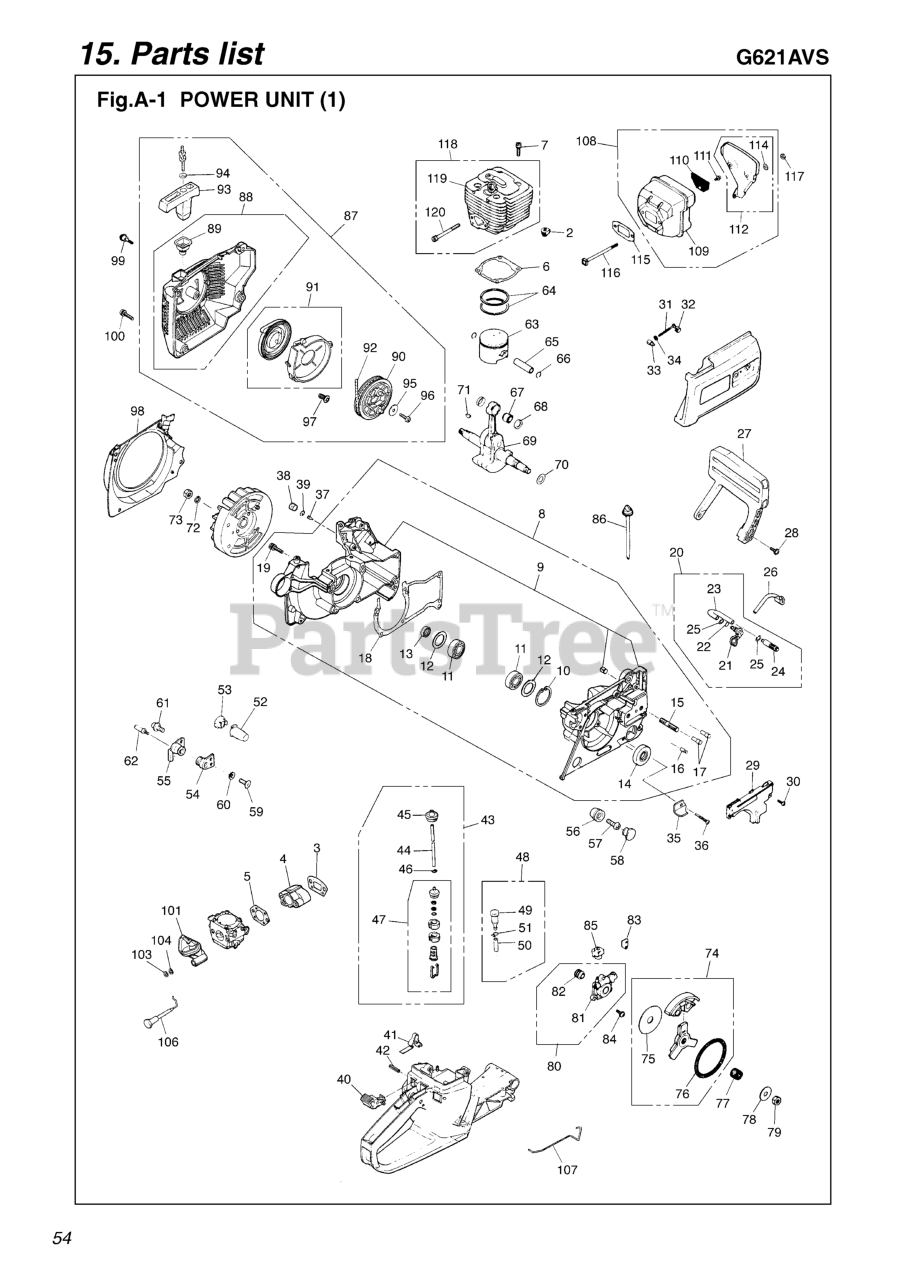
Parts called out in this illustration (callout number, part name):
2	GROMMET
3	GASKET
4	INSULATOR
5	GASKET
6	GASKET
7	BOLT
8	CRANKCASE-ASSY
9	CRANKCASE COMP
10	SNAP RING
11	BEARING
12	RING
14	SEAL
15	STUD
16	PIN
17	PIN
18	GASKET
19	BOLT
20	OIL PIPE COMP
21	PIPE
24	WEIGHT
26	PIPE
27	GUARD
28	SCREW
29	COVER
30	SCREW
31	SCREW
32	STOPPER
33	NUT (A)
34	WASHER
35	CATCHER
37	VALVE
38	SEAL
39	CLIP
40	LEVER
41	SPRING
42	PIN
43	FUEL PIPE ASSY
44	PIPE
45	GROMMET
46	CLIP
47	FILTER ASSY
48	BREATHER ASSY
49	BREATHER
51	CLIP
52	FRONT DAMPER
53	CAP
54	REAR DAMPER-R
55	REAR DAMPER-L
56	REAR DAMPER-B
57	SCREW
58	CAP
59	SCREW
61	SCREW
63	PISTON
64	RING
65	PIN
66	RING
67	BEARING
68	WASHER
69	CRANKSHAFT COMP
70	SHIM
71	KEY
72	WASHER
73	NUT
74	CLUTCH ASSY
75	PLATE
77	BEARING
78	WASHER
79	NUT
80	OIL PUMP ASSY
81	BODY
82	WORM
83	GASKET
85	GROMMET
86	SHAFT
87	STARTER ASSY
88	CASE COMP
89	GUIDE
90	REEL
91	SPRING COMP
92	ROPE
96	SCREW
98	COVER
99	SCREW
100	SCREW
101	MANIFOLD
103	WASHER
104	WASHER
106	ROD
107	ROD
108	MUFFLER ASSY
109	MUFFLER
110	SPARK ARRESTER
112	COVER SEAT
114	WASHER
115	GASKET
116	BOLT
117	NUT
118	CYLINDER SET
120	BOLT
